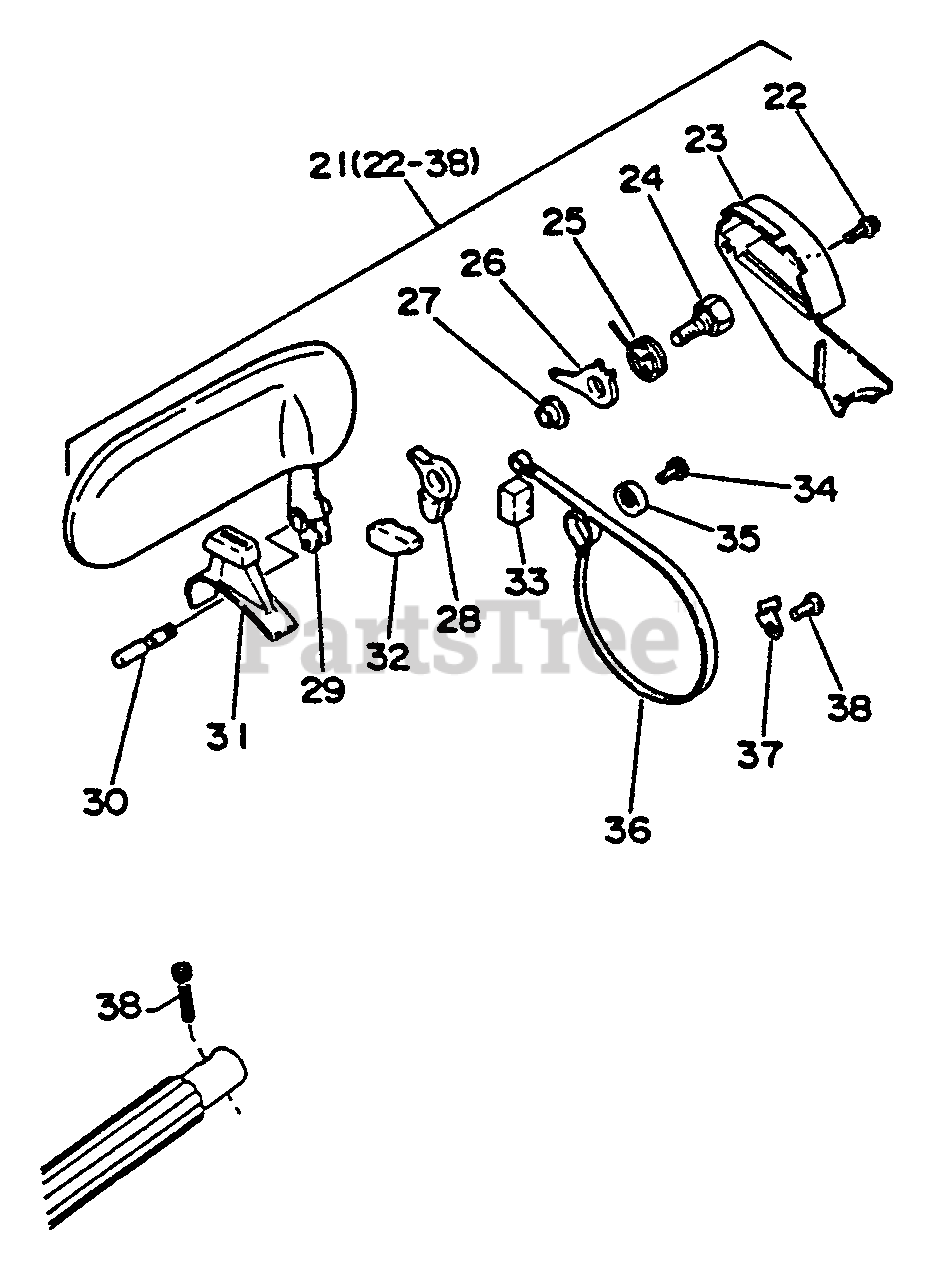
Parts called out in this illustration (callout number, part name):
21	CHAIN BRAKE ASSY
22	SCREW 4×12
25	SPRING, RETURN
28	CONNECTOR
29	HANDLE
31	COVER, BRAKE
32	RESET, BRAKE
33	SEAL
34	SCREW 5×10
35	ADJUSTER, BRAKE BAND
36	BAND, BRAKE
37	RETAINER, BRAKE BAND
38	BOLT 5×25
